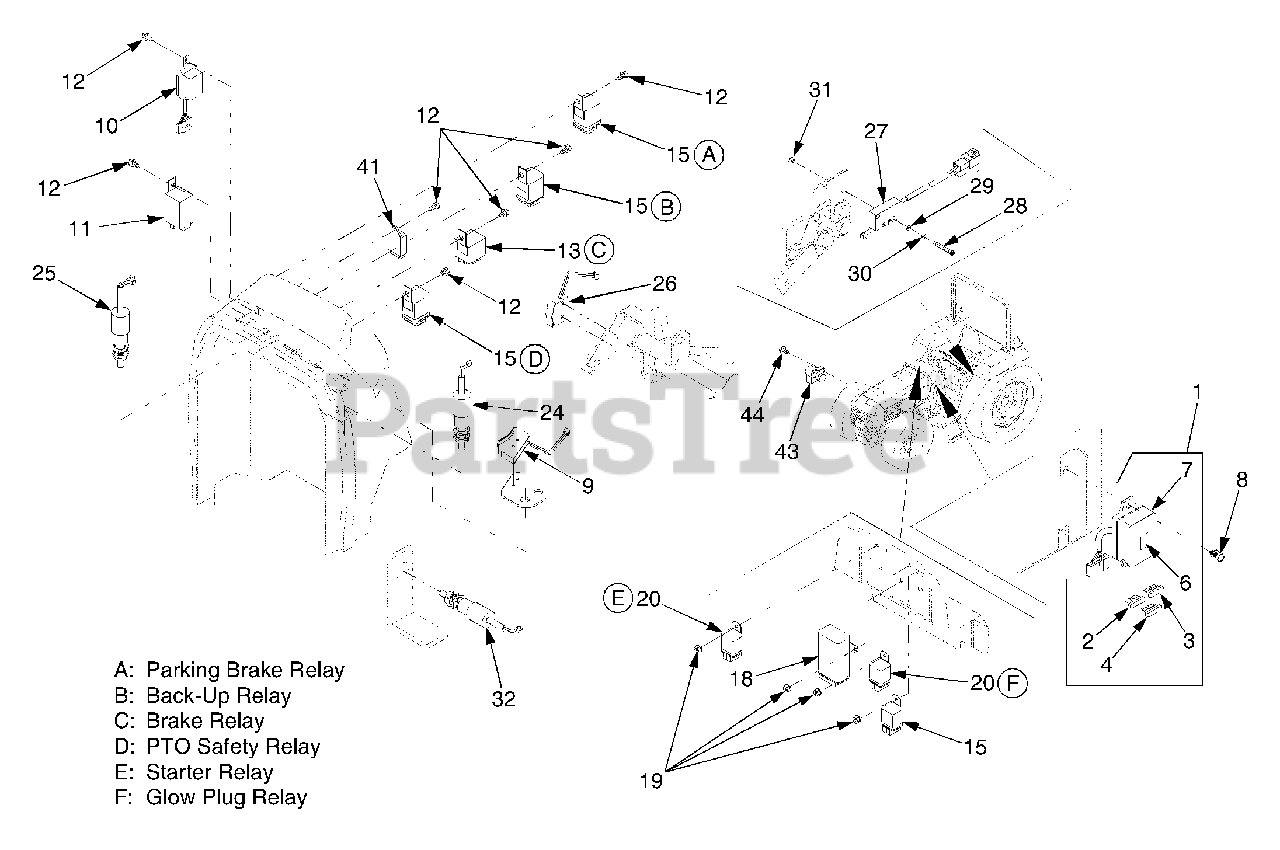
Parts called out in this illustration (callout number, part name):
1	Fuse Box Ass'y
2	Fuse (25a)
3	Fuse (20a)
9	Switch, Micro
10	Relay, Timer
11	Unit, Flasher
18	Controller, Preheater
20	Relay
24	Switch, Safety Starter
25	Stop Switch Ass'y
26	Switch, Micro
27	Switch, Micro
29	Washer, Plain
30	Washer, Spring
32	Safety Starter Ass'y
41	FFT Controller
43	Sensor, Pick Up
